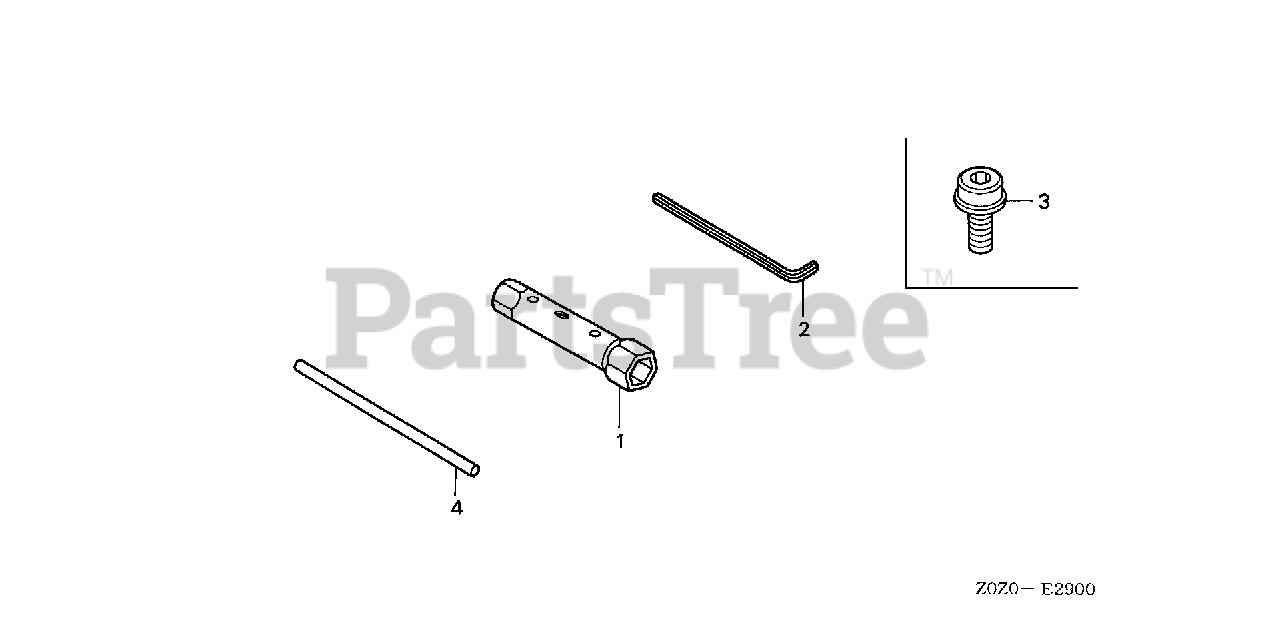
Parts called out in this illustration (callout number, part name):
1	WRENCH, SPARK PLUG
2	WRENCH, HEX. (4MM)
3	BOLT, SOCKET (5X9)
4	BAR A, HANDLE
